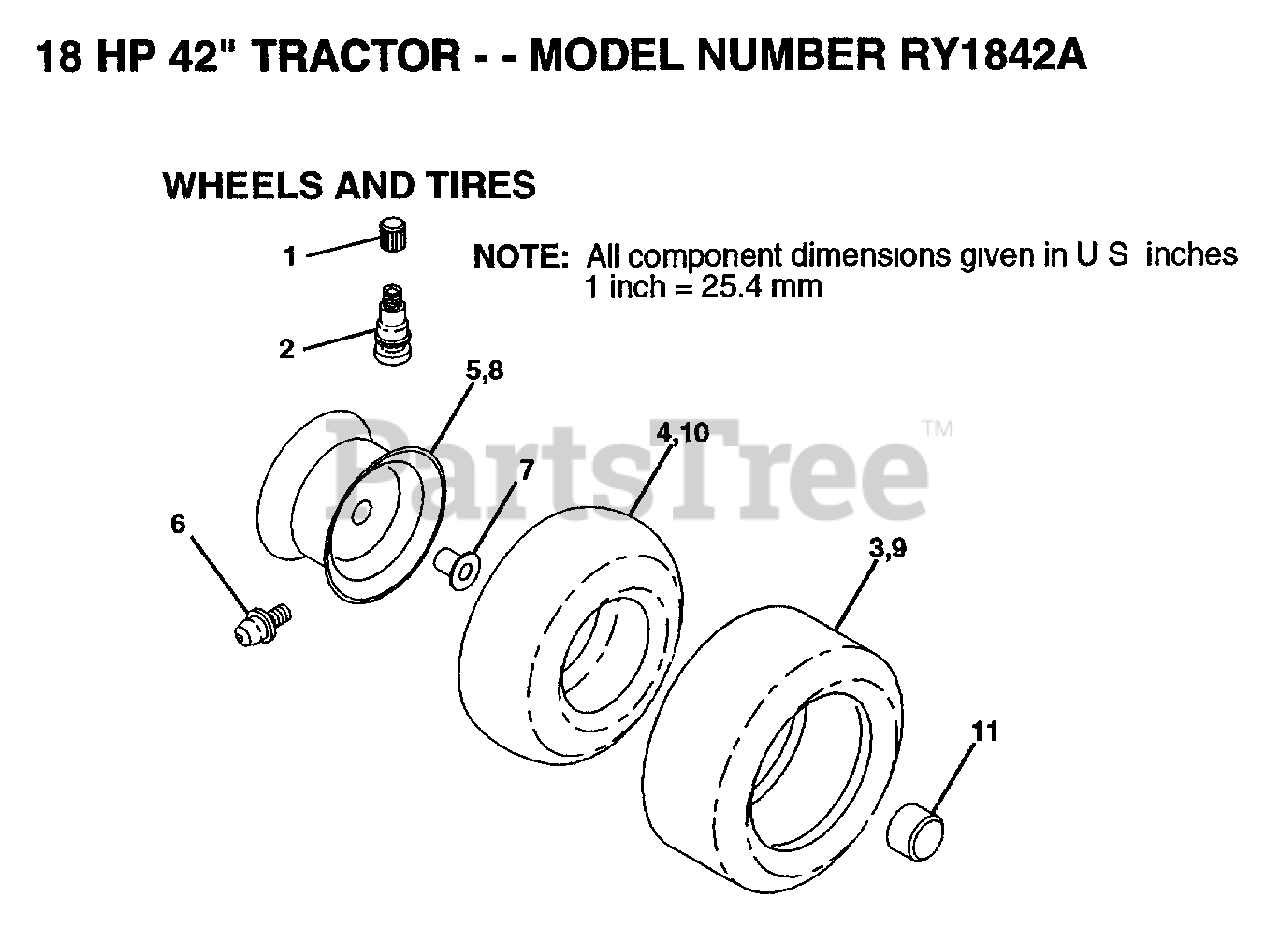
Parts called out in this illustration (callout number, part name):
1	VALVE CAP
2	VALVE STEM LT
4	TUBE.5.3/4.5/6
6	FITTING LT
10	TUBE.18X9.5-8
11	HUB CAP
